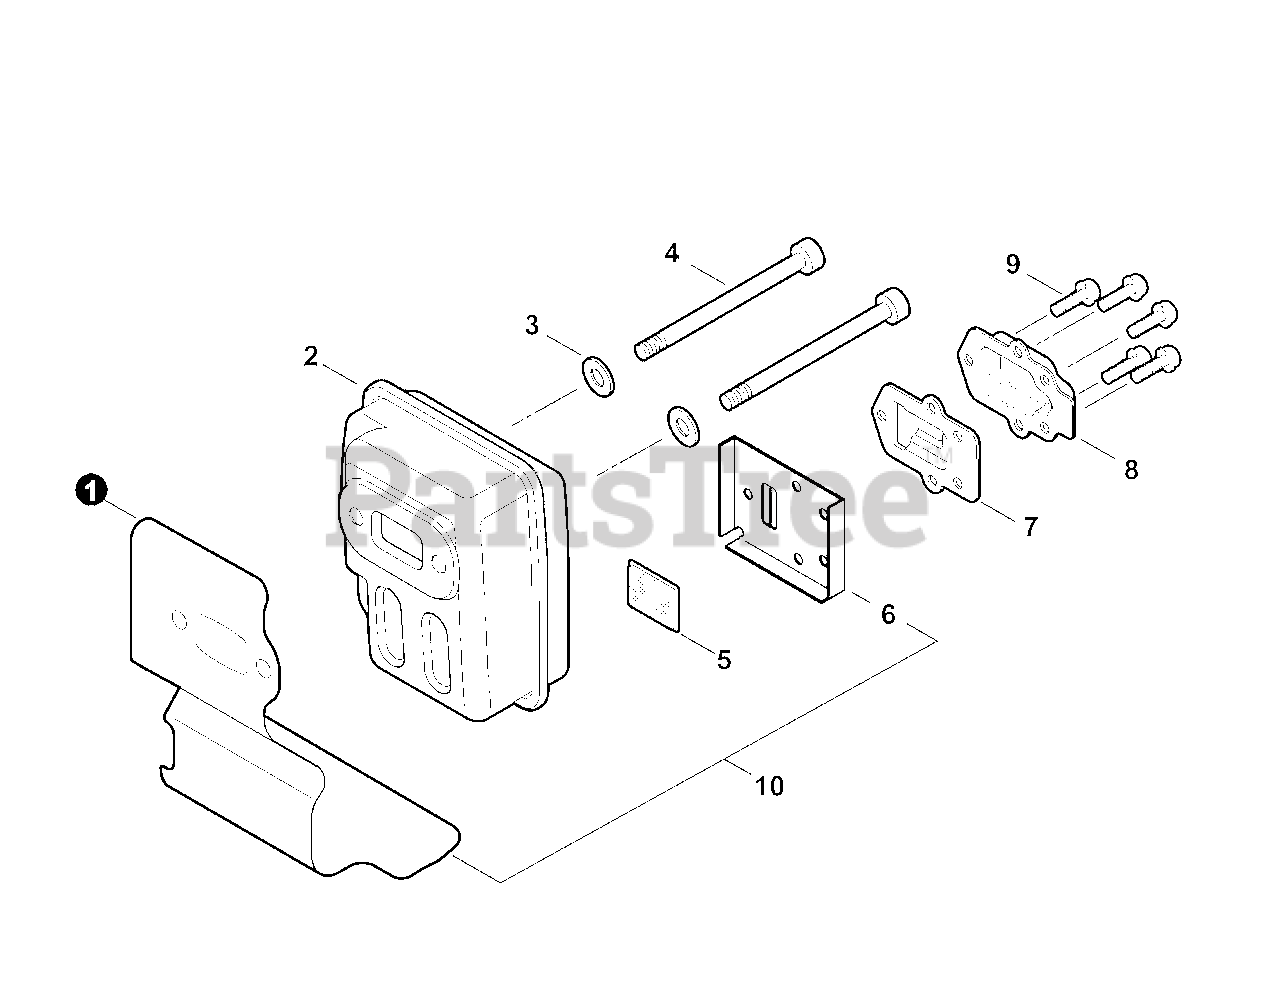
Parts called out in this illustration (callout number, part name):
1	HEAT SHIELD, EXHAUST
2	MUFFLER
3	WASHER 5.5×12×0.8
5	SCREEN, SPARK ARRESTER
6	GASKET, EXHAUST
7	GUIDE, EXHAUST
8	OUTLET, EXHAUST
9	SCREW 4×10
10	GASKET KIT
